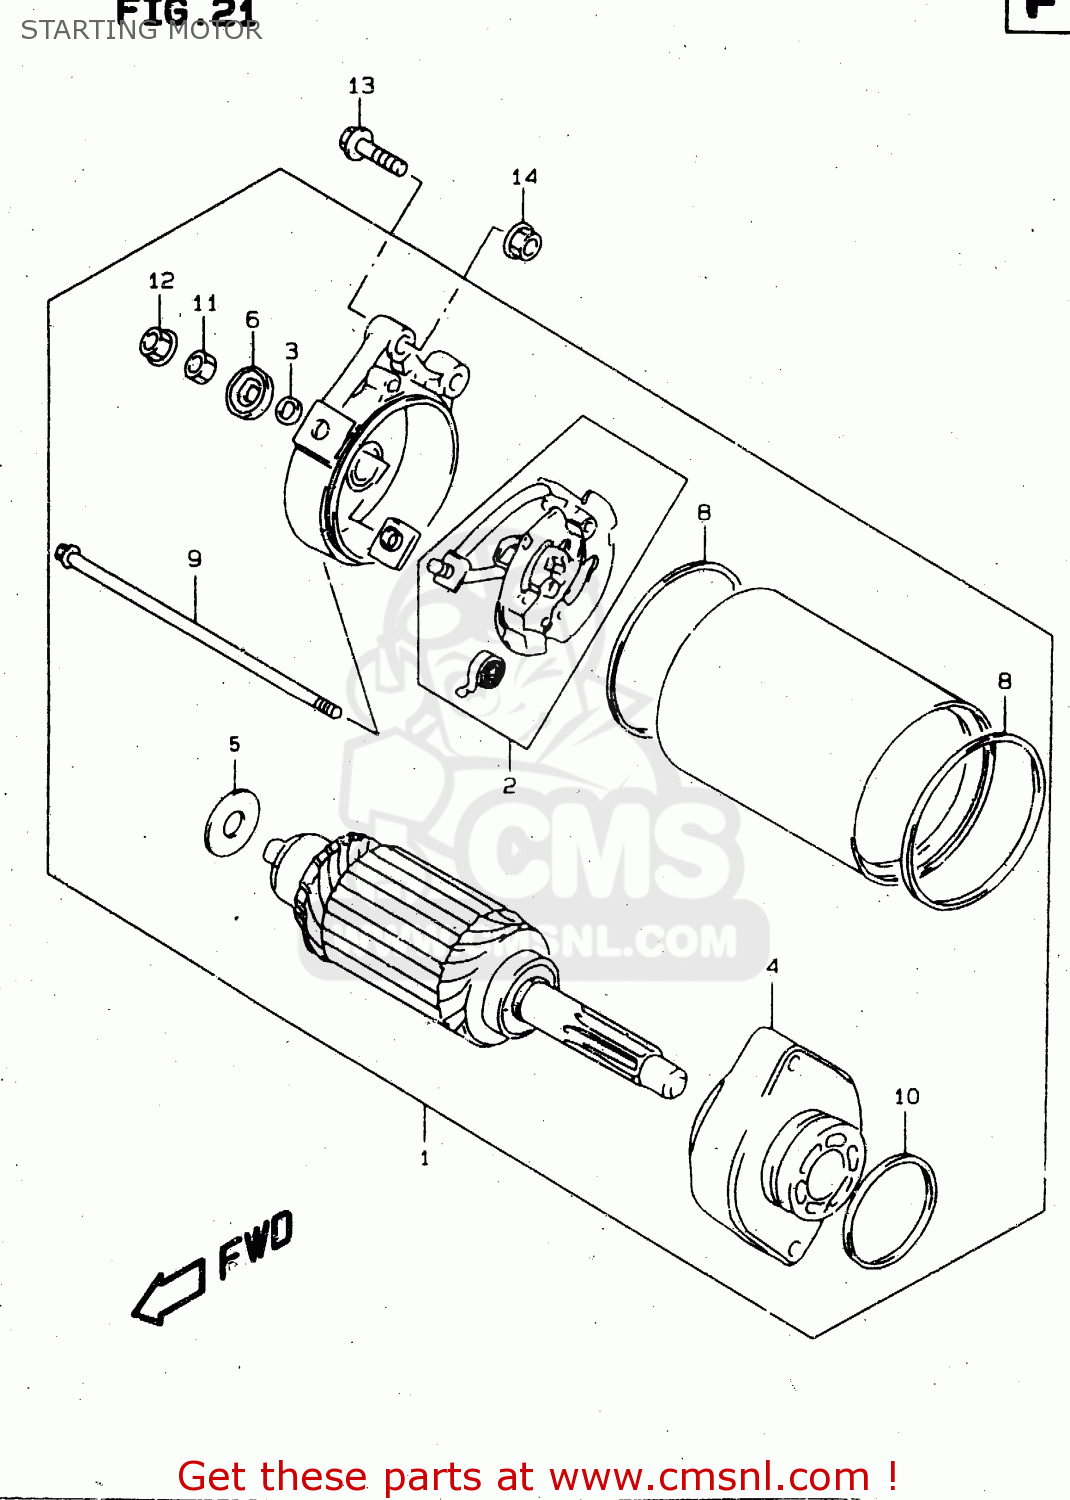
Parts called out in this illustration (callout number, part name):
1	MOTOR ASSY,STARTING
2	HOLDER SET,BRUSH
3	O RING
4	BRACKET SET
5	SHIM SET,STARTING MOTOR
6	BUSHING
7	BUSHING
8	O RING
9	BOLT
10	O-RING (D:2.1 ID:34.7)
11	NUT
12	NUT
13	BOLT
14	NUT
